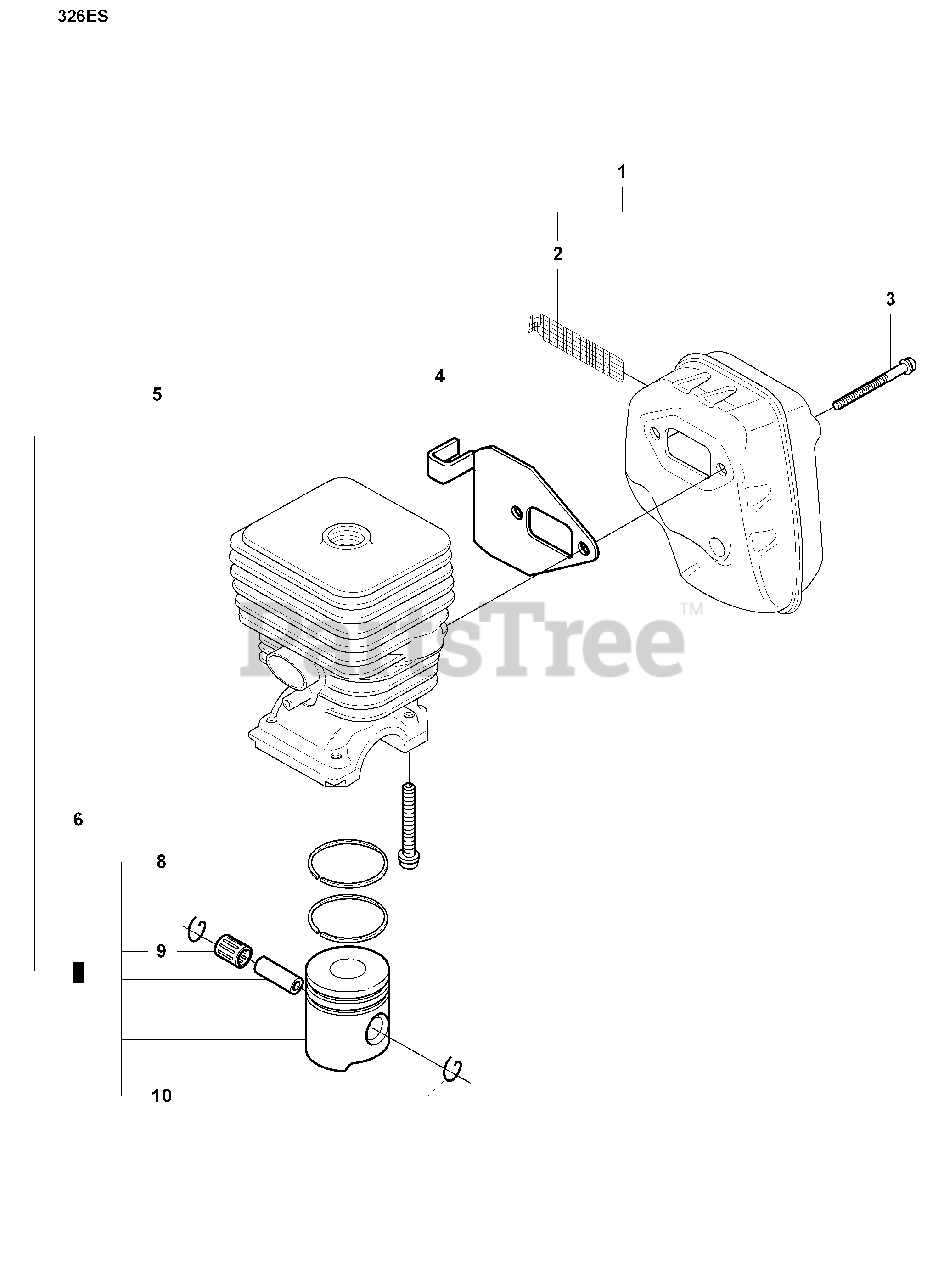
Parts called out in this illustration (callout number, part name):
1	MUFFLER
2	SPARK ARRESTOR SCREEN
5	CYLINDER
6	%SCREW
8	PISTON RING
